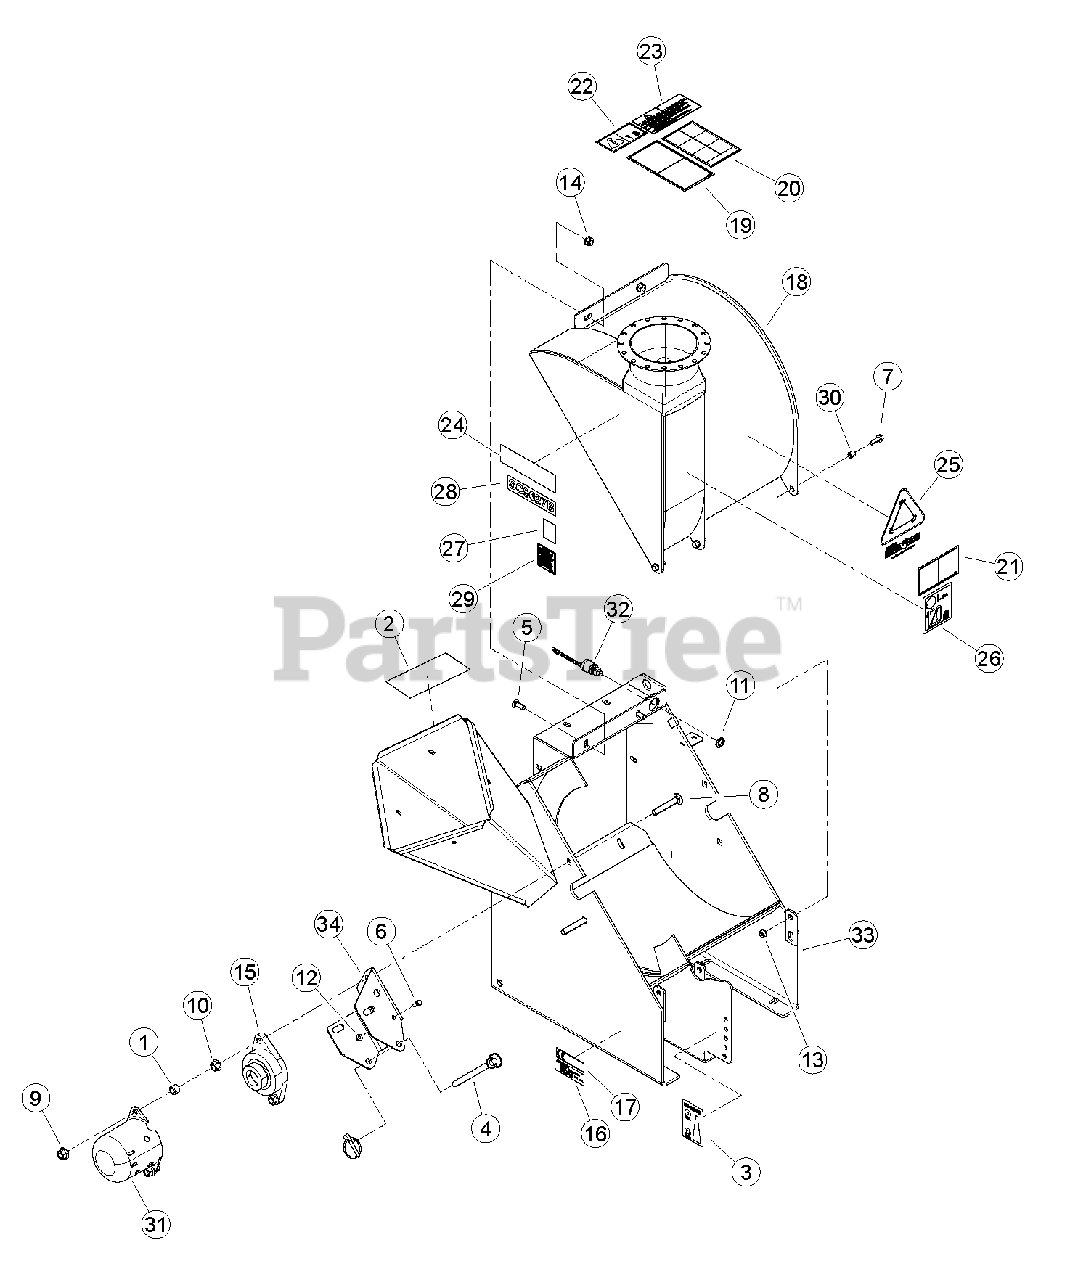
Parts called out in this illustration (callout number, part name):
1	BUSHING, 1/2ID X 3/4 OD X 17/32 LNST
2	DECAL, BLADE DANGER ISO
3	DECAL, SHRED SIZE
4	PIN, HITCH 1/2 X 6-1/2 W/ LYNCH
5	BOLT, 3/8-16 X 1 GR5 CRG
6	BOLT, 1/4-20 X 3/4 HWH GR5 CZP
7	BOLT, 5/16 X 1 FLANGE NC
8	BOLT, 1/2 X 3.00 GR5 CRG ZP
9	NUT, 1/2-13 NYLOCK FLANGE
10	NUT, 1/2 SPIRAL LOCK NC ZP
11	NUT, 5/8-32 JAM
12	NUT, 1/4-20 NYLOCK FLANGE
13	NUT, 5/16-18 NYLOCK FLANGE
14	NUT, 3/8-16 NYLOCK FLANGE
15	BEARING, 2 BOLT FLANGE 1-1/2" BORE (CE COMPLIANT ONLY)
16	DECAL, ATLANTIC BRIDGE LTD INFO (CE COMPLIANT ONLY)
17	DECAL, SC5627B INFORMATION
18	ASSEMBLY, HOUSING TOP 5" C/S/B
19	DECAL, KNIFE ACCESS ISO
20	DECAL, OPERATING INSTRUCTIONS ISO
21	DECAL, DISCHARGE ISO
22	DECAL, MAINTENANCE ISO
23	DECAL, MUTILINGUAL MANUAL
24	DECAL, ECHO BEARCAT 6.82 X 1.90
25	DECAL, SHRED IT
26	DECAL, 120 DB
27	DECAL, ECHO BEARCAT QR CODE
28	DECAL, MODEL SC5627B
29	DECAL, SPARK ARRESTOR
30	SPACER, .50 X .50
31	CAP, LARGE SHAFT
32	ASSEMBLY, SEALED SWITCH
33	WELDMENT, C/S BOTTOM
34	PLATE, ROTOR LOCK
